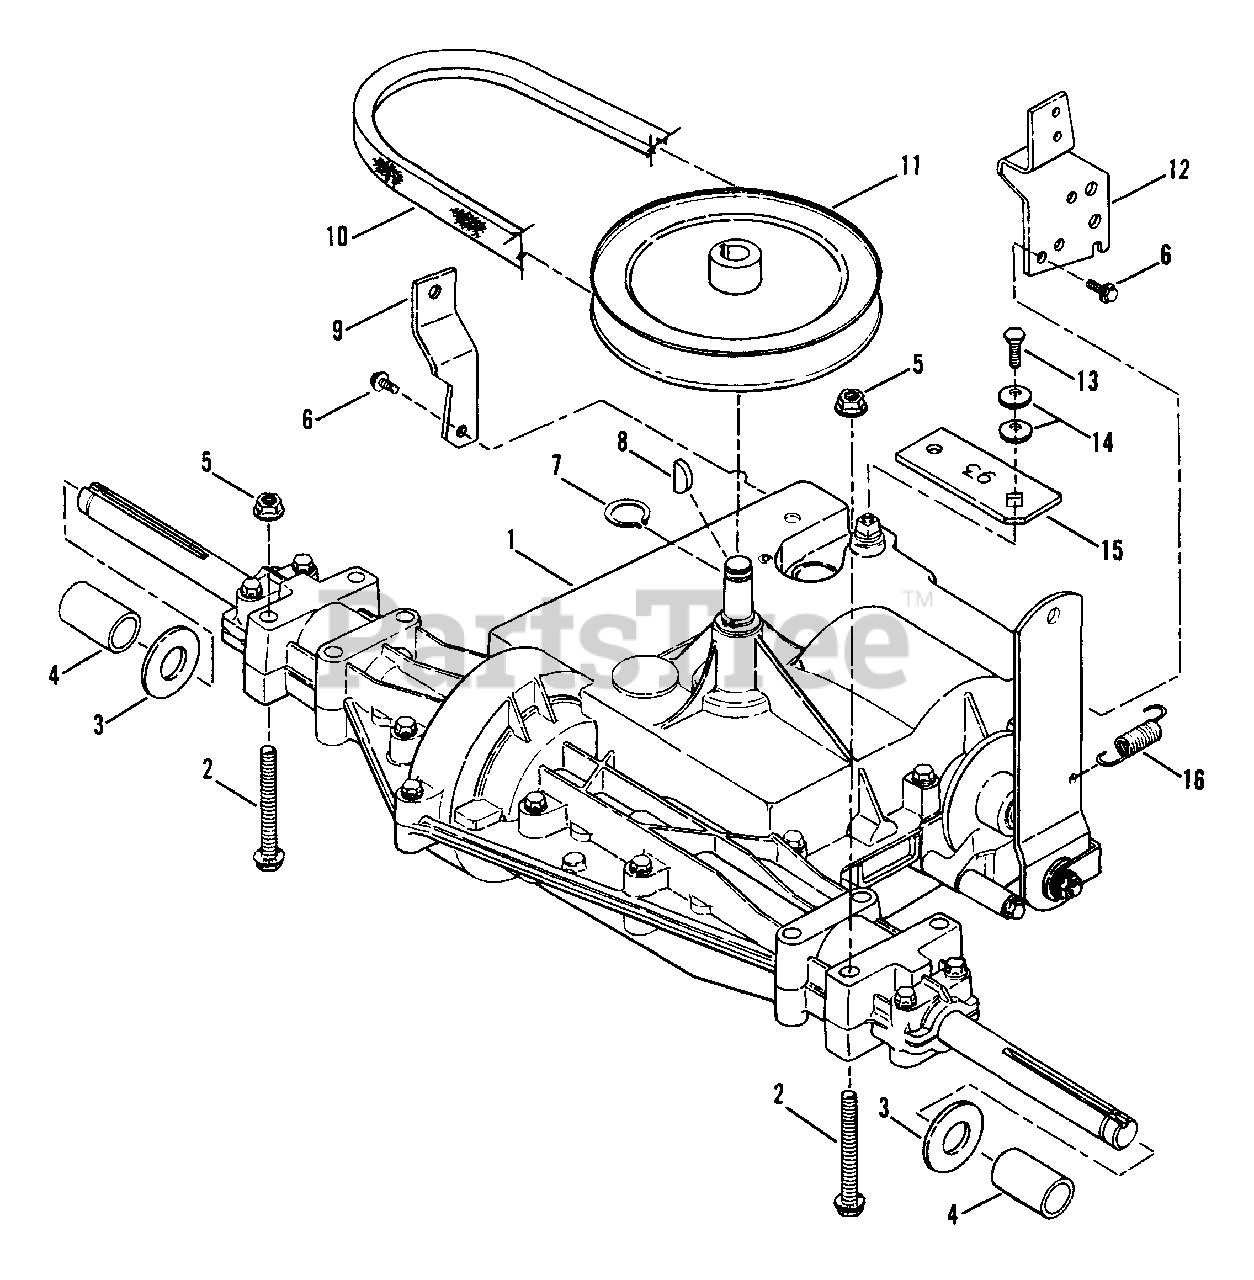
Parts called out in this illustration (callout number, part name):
1	TRANSAXLE, Peerless Model 930, 6-Speed
2	BOLT, 5/16-18 x 2 1/4" Hex Flange Lock
3	WASHER, Flat
5	NUT, 5/16-18 Hex Flange Lock
6	SCREW, 5/16-18 x 5/8" Hex Washer Head, Self-Tapping
7	RING, Retaining
8	KEY, Woodruff, 3/16 x 3/4", No. 9
9	BRACKET, Torque
10	BELT, P930, Traction Drive (HA 97.75)
11	PULLEY, Drive
12	BRACKET, Axle/Spool
13	BOLT, 1/4-28 x 5/8" Hex Head
14	WASHER, Bellville
15	ARM, Shift Link Lever
16	SPRING, Brake Return
